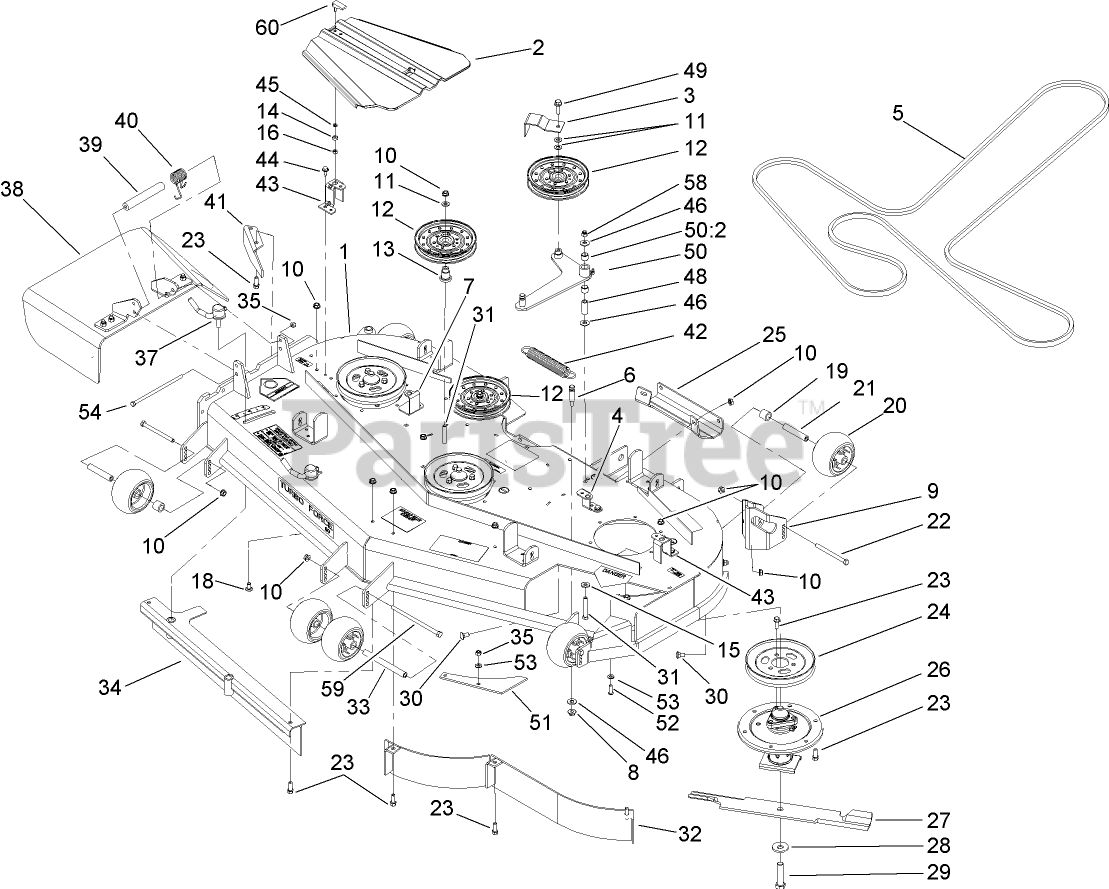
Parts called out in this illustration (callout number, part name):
1	DECK DECAL ASM
2	COVER-BELT
3	GUIDE-BELT
4	BRACKET-COVER, TALL
5	BELT-V
6	PIN-THREADED, SPRING ANCHOR
7	BRACKET-COVER
8	NUT-HF
9	MOUNT-WHEEL, LH
10	NUT-HHF, WHIZ
11	WASHER-FLAT
12	Idler-Flat
13	MOUNT-PULLEY
14	BUSHING-LATCH, SWELL
15	WASHER-BELLEVILLE
16	NUT-LOCK, HH
18	SCREW-CARR
19	TUBE-SPACER
20	ROLLER-SCALP, ANTI
21	TUBE-SPANNER
22	SCREW-HH
23	SCREW-HWH
24	Pulley
25	Plate-Skid
26	SPINDLE ASM
27	BLADE-HI FLOW
28	Washer-Blade Bolt, Heavy
29	Screw-Cap
30	SCREW-CARR
31	SCREW-HH
33	SPACER-WHEEL
35	NUT-LOCK, NI
37	LEVER ASM
38	RUBBER DEFLECTOR ASM
39	SPACER
40	SPRING-TORSION
41	BAFFLE-DISCHARGE
42	SPRING-EXTENSION
43	BRACKET-COVER
44	SCREW-HWHTF
45	WASHER
46	WASHER-FLAT
48	BUSHING
49	SCREW-HHF
50	DECK IDLER ARM ASM
50:2	SLEEVE-BEARING
51	PLATE-TURBO
52	SCREW-HSBH
53	WASHER-SPRING
54	SCREW-HH
58	NUT-LOCK, NI
59	SCREW-HH
60	HANDLE-LATCH, SWELL
